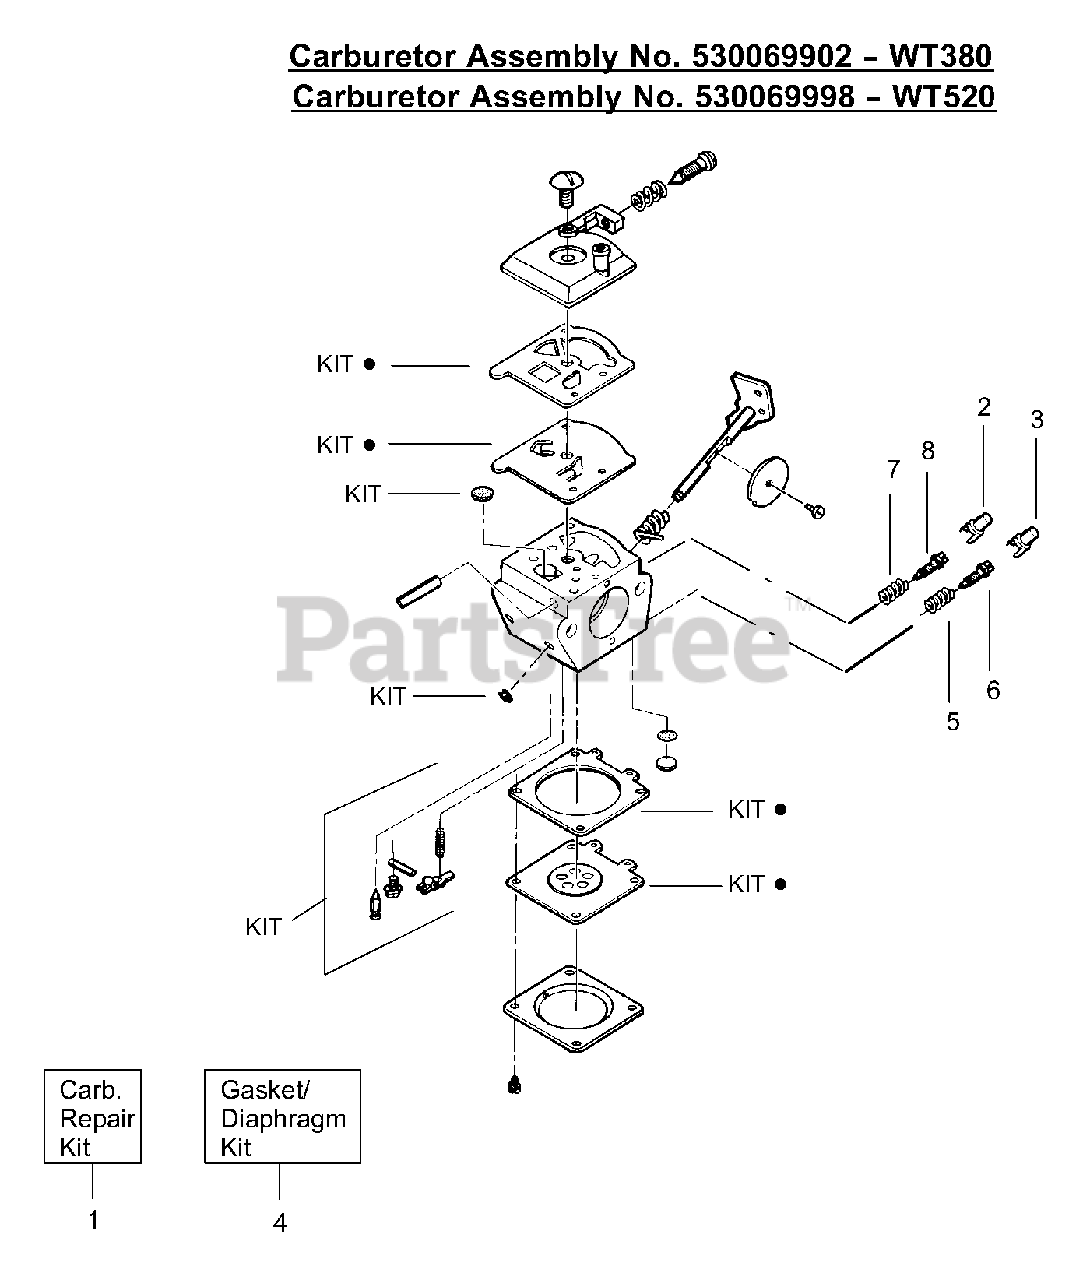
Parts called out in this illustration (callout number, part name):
1	Carburetor Repair Kit
2	Limiter Cap (High-Red)
3	Limiter Cap (Low-Blue)
4	Gasket/Diaphragm Kit
5	Needle Spring-Low Speed
6	Needle-Low Speed
7	Needle Spring-High Speed
8	Needle-High Speed
530069902	Carburetor Assembly WT380
530069998	Carburetor Assembly WT520
